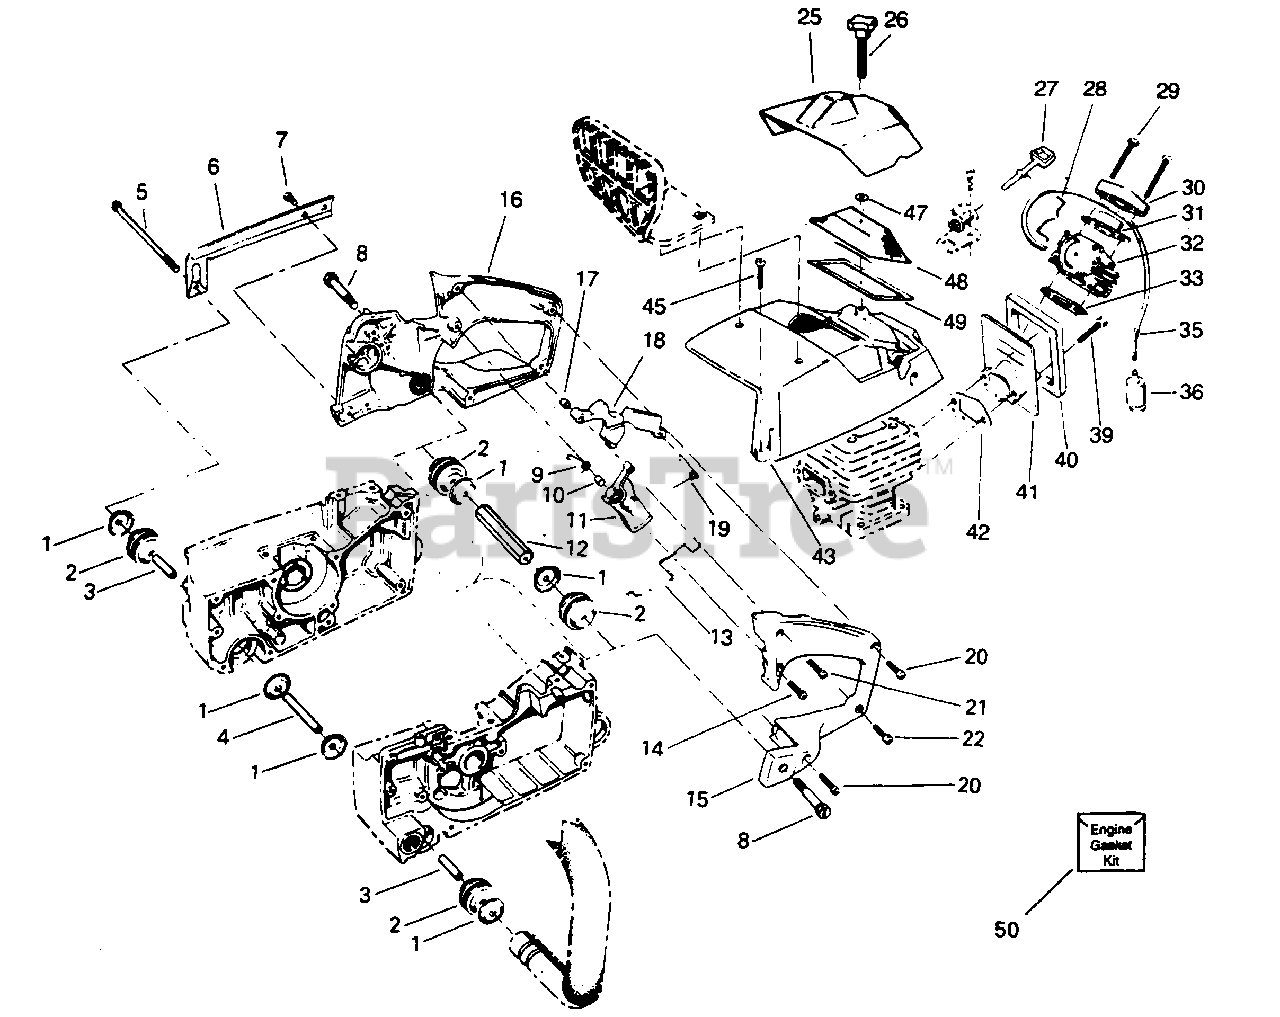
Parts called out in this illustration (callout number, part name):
1	Cup Isolator
2	Isolator-Powerhead Rear Handle
2	Use on Guide Bar Powerhead
2	Use on Bow Guide Powerhead
3	Spacer-Front Handlebar Isolator Mount
4	Spacer-Front Handlebar-Center-Isolator Mount
5	Screw - 1/4-20x5-5/16
6	Handle Brace-See
7	Screw - 1/2-20 x 3/4 Button Hd.
8	Shoulder Screw 1/2-20 - Isolator
9	Spring-Trigger
10	Bushing-Trigger
11	Throttle-Trigger
12	Spacer-Isolator (Center)
13	Wire Throttle
14	Shoulder Screw - 10-24x5/8 - Fil. Hd. - Throttle Trigger
15	Rear Handle Left
16	Rear Handle Right
17	Bushing-Throttle Lock
18	Throttle Lock
19	Spring-Throttle Lock
20	Screw - 10-24x13/16 - Fil. Hd. Rear Handle Lower
21	Screw - 8-32x13/16 - Fil. Hd. Rear Handle Throttle Lock
22	Screw - 8-32x9/16 - Fil. Hd. Rear Handle Lower
25	Cover-Carburetor
26	Knob-Carburetor Cover
27	Choke Rod
28	Wire Choke
29	Screw - 10-24x11/16 - Fil. Hd. Carburetor to Adaptor
30	Seal-Adaptor Shield
31	Bracket-Carburetor Seal
32	Carburetor
33	Gasket-Carburetor to Adaptor
35	Line Kit
36	Fuel Pick-up Ass'y
39	Screw - 10 - 24 x 1-3/16 - Hex Hd. - Adaptor to Cylinder
40	Seal-Carburetor Adaptor
41	Carburetor Adaptor
42	Gasket - Adaptor to Cylinder
43	Cylinder Shield
45	Screw - 10-24x5/8 - Fil. Hd. Cylinder Shield to Crankcase
47	Retainer-Carb. Cover Knob
48	Air Filter
49	Gasket - Air Filter
50	Kit - Engine Gasket
